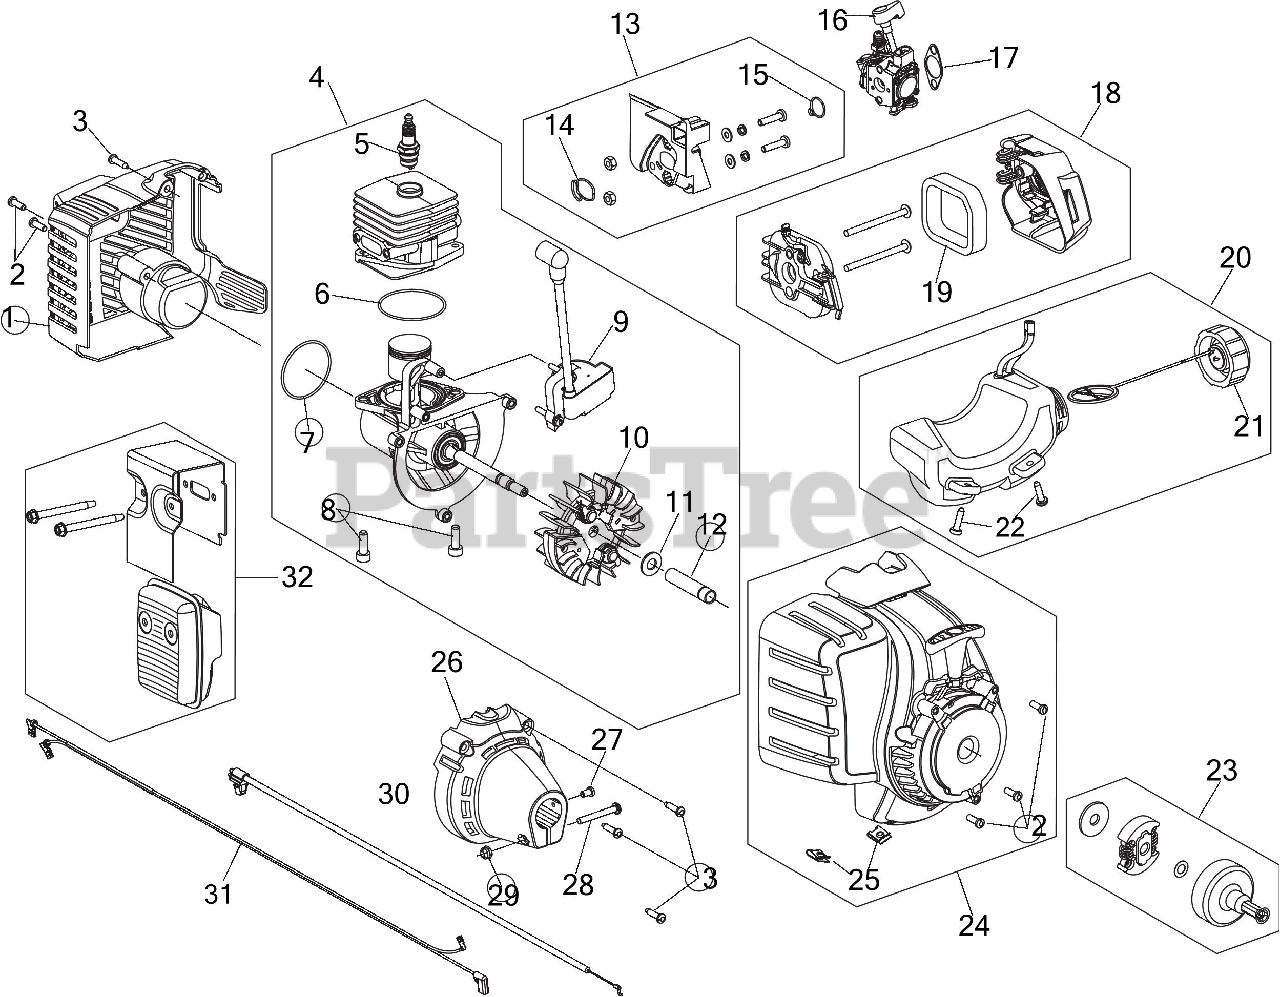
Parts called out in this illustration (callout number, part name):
1	REAR ENGINE CVR
2	SCREW:10-32X.562:#8P
3	SCREW, #8-16X.750 PH
4	SHORTBLOCK
5	SPARK PLUG
6	O-RING
7	O-RING
8	SCREW, 1/4-20 x .75
9	MODULE 27CC DIG
10	FLYWHEEL ASSEMBLY
11	BELL WASHER
12	SPACER
13	INTAKE ASSEMBLY
14	O-RING
15	O-RING
16	CARBURETOR
17	GASKET CARB
18	AIRCLEANER COVER ASSEMBLY
19	AIR FLITER
20	FUEL TANK ASSEMBLY
21	FUEL CAP ASSEMBLY
22	SCREW 10-6 x .75
23	SMALL CLUTCH ASSEMBLY W/SMALL DRUM
24	STARTER HOUSING ASSEMBLY
25	NUT, TINNERMAN U-T
26	CLUTCH COVER
27	SCREW, 8-32 x .312 P
28	SCREW
29	CLAMP NUT (NOT SERVICEABLE)
30	THROTTLE CABLE
31	WIRE LEADS
32	MUFFLER ASSEMBLY
